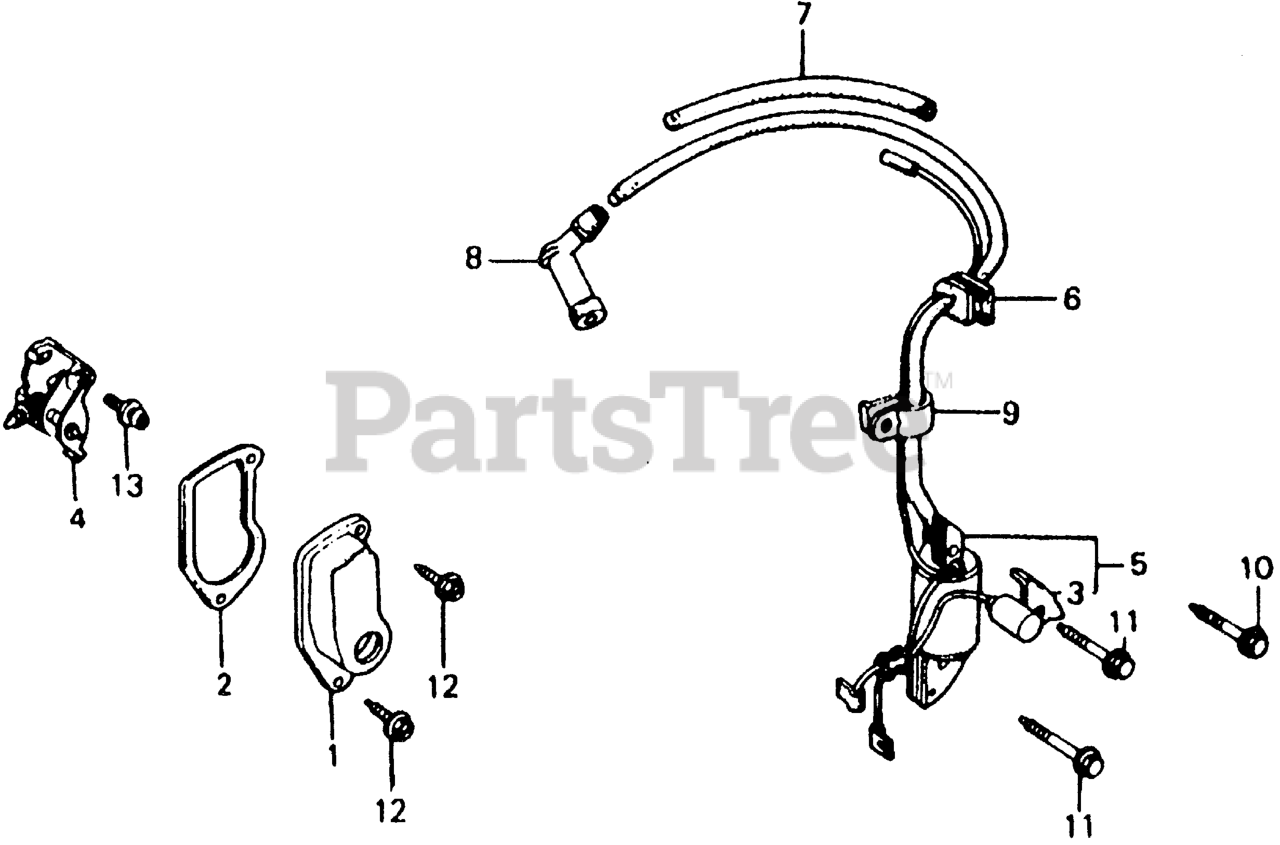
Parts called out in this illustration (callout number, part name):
1	COVER, POINTS
2	GASKET, POINT COVER (Honda Code 0636738). (NOT AVAILABLE)
3	CONDENSER
4	POINTS ASSY.
5	COIL ASSY., IGNITION
6	GROMMET, WIRE
7	TUBE, IGNITION RUBBER
8	CAP ASSY., NOISE SUPPRESSOR (NOT AVAILABLE)
11	BOLT, FLANGE (6X32)
12	BOLT, FLANGE (5X10)
13	SCREW-WASHER (5X12)
